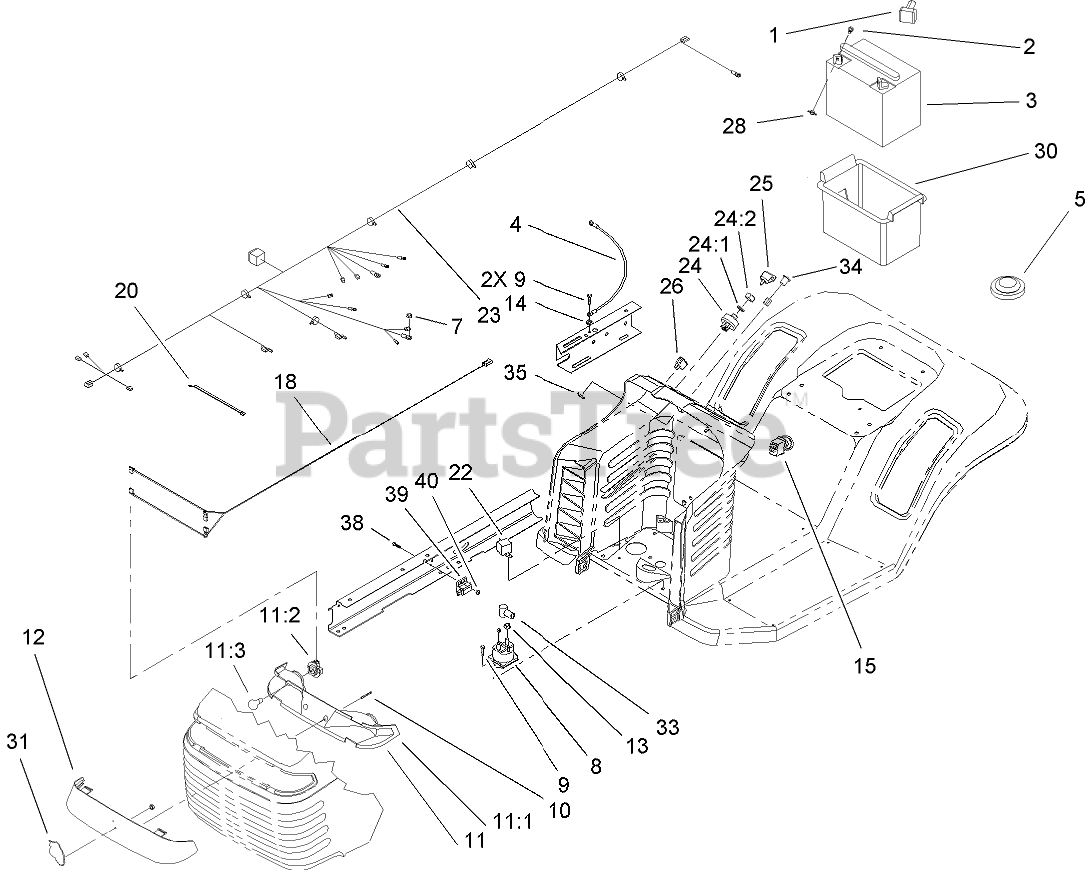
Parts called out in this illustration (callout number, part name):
1	BOOT-TERMINAL
2	SCREW-HH
3	BATTERY-155 CCA
4	WIRE ASM
5	SWITCH-SEAT
7	NUT-KEPS
8	SOLENOID-STARTER
9	SCREW-HWH
11	HEADLIGHT REFLECTOR ASM
11:1	REFLECTOR-LIGHT
11:2	SOCKET-HEADLIGHT
11:3	BULB
12	LENS-HEADLIGHT
13	NUT-KEPS
14	WASHER-LOCK/EXT
15	SWITCH-PTO
18	HARNESS-HEADLIGHT
20	TIE-CABLE
22	RELAY
23	HARNESS-WIRE
24	Key Switch ASM
24:1	WASHER-TOOTH, INTERNAL
24:2	NUT-HH
25	KEY-IGNITION
26	SWITCH-ROCKER
28	NUT-WING
30	BOX-BATTERY
31	EMBLEM
33	BOOT-INSULATOR, TERMINAL
34	LIGHT-INDICATOR
35	NUT-PUSH-ON, CIRCULAR
38	SCREW-HSH
39	SWITCH-POLE, SINGLE
40	NUT-LOCK, NI
